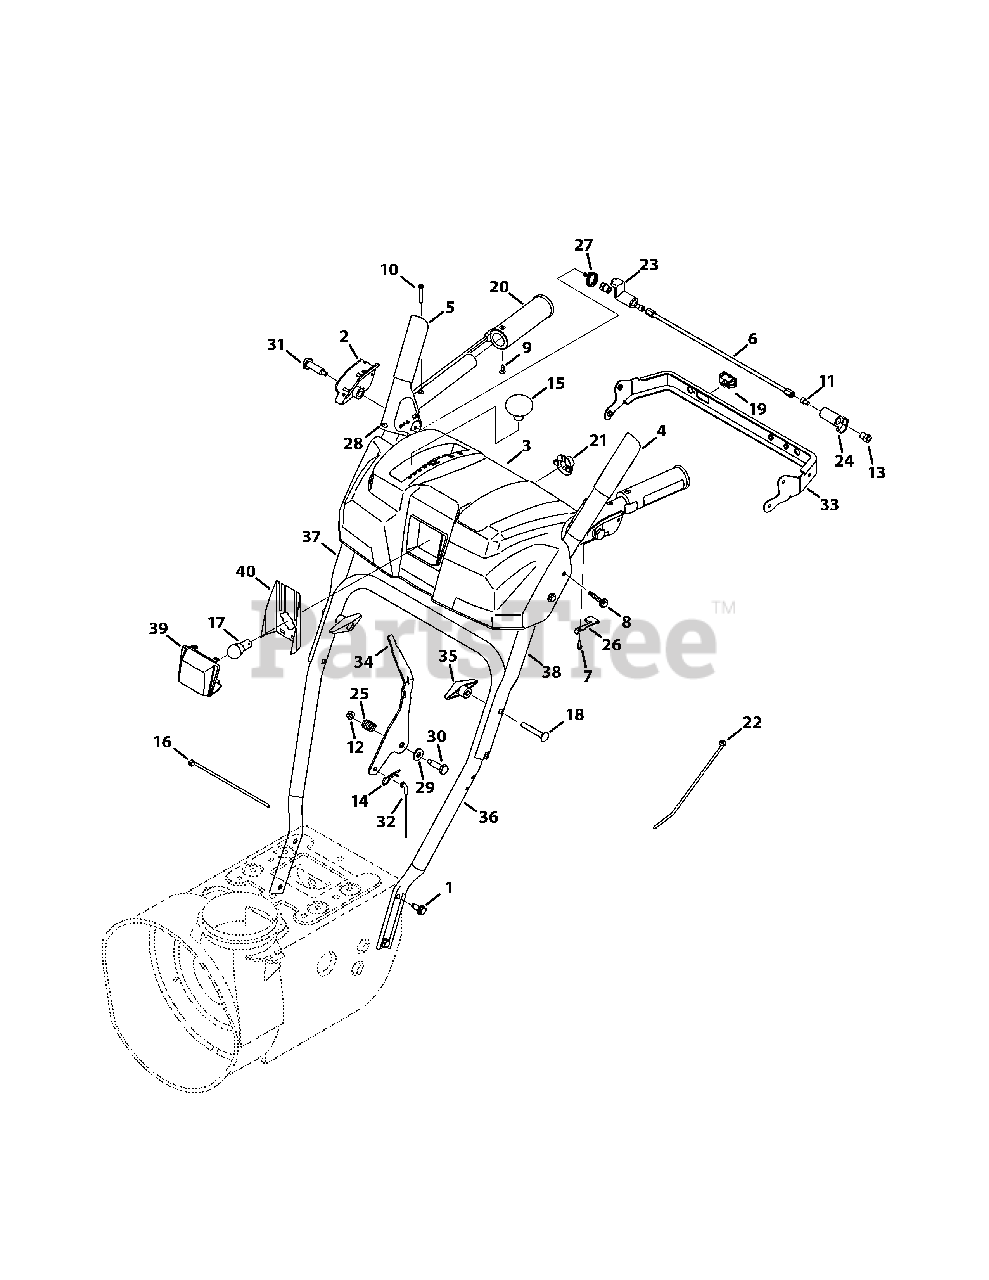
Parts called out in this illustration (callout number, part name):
1	Screw, Taptite, 5/16-18 x .750
2	Clutch Lock, RH
2	Clutch Lock, LH
3	Handle Panel w/o Light
4	Auger Engage
5	Drive Engage
7	Screw, Plastite, 8-16 x .50
8	Screw, Taptite, 1/4-20 x 1.625
9	Screw, 10-16 x 0.625
10	Screw, 10-24 x 1.375
11	Screw, 1/4-20 x .50
12	Nut, Flange Lock, 1/4-20
13	Nut, Hex, 1/4-20
14	Click Pin, .092 x 1.64
15	Shift Knob
16	Cable Tie, 7"
17	Lamp, 12.8V
18	Screw, Carriage, 5/16-48 x 2.25
19	Heated Grip Switch
21	Lamp Socket
22	Cable Tie, Push Mount
23	Plate, Lock
24	Cam, Clutch Lock
25	Compression Spring, .39 x .60 x .88
26	Clutch Lock Spring
27	Torsion Spring, 0.8156 x .3038
28	Rubber Bumper
29	Washer, Flat, .385 x .87
30	Screw, Shield, .374 x 1.05
31	Screw, Shoulder, .437 x 1.345 x 1/4-20
32	Speed Selector Cable
33	Panel Bracket
35	Wing Knob
36	Lower Handle
37	Upper RH Handle
38	Upper LH Handle
39	Lens Panel, Troy-Bilt
40	Lens Label, Troy-Bilt
